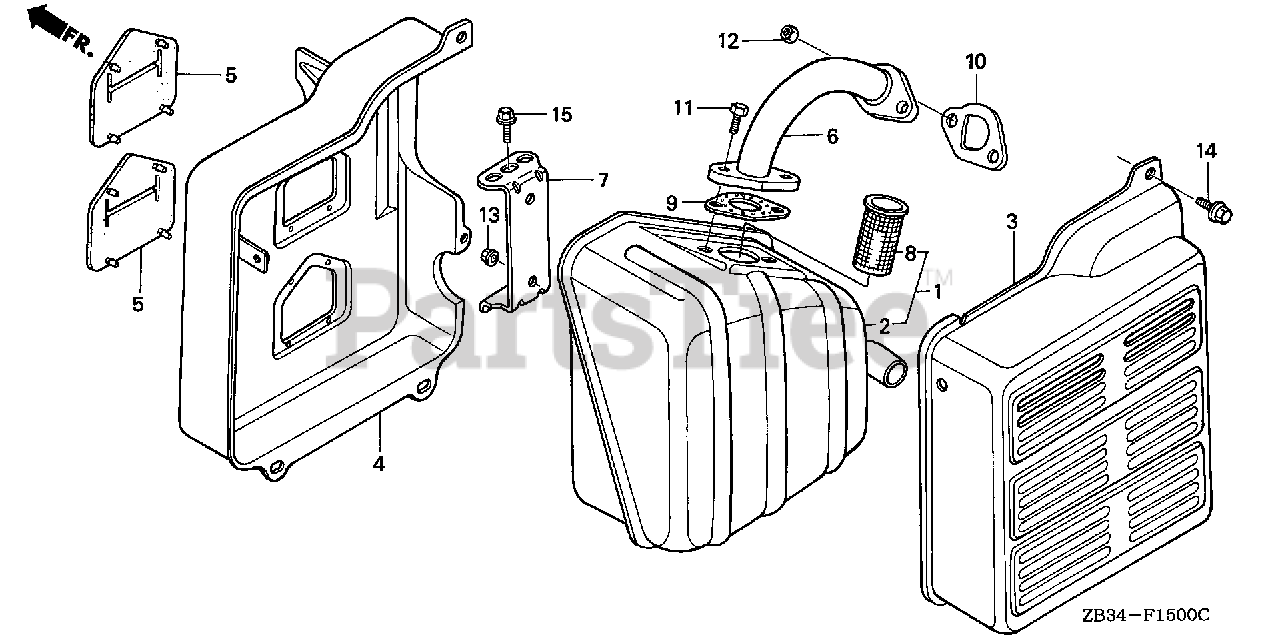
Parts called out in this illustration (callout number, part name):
2	MUFFLER
3	PROTECTOR, MUFFLER (OUTER)
4	PROTECTOR, MUFFLER (INNER)
5	SEAL, MUFFLER PROTECTOR
7	STAY, MUFFLER
8	ARRESTER, SPARK
9	GASKET, MUFFLER
10	GASKET, MUFFLER
11	BOLT, HEX. (8X20)
12	NUT, HEX. (8MM)
13	NUT, FLANGE (6MM)
14	BOLT, FLANGE (6X12)
15	BOLT, FLANGE (8X16)
